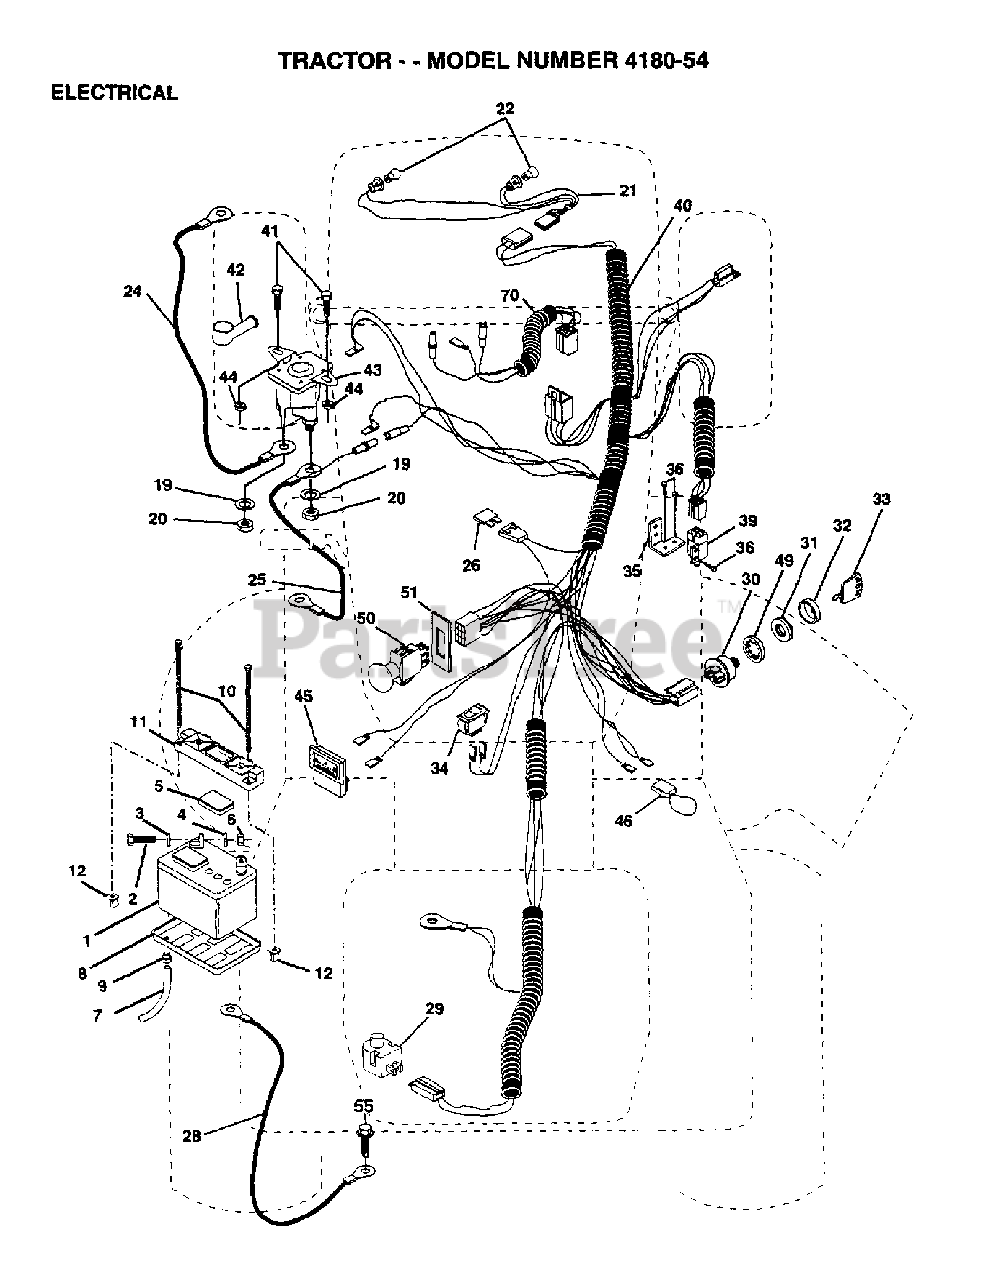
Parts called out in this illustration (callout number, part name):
1	BATTERY
2	BOLT.HEX.1/4.X.3/4.DICHROMATE
3	WASHER
4	LOCKWASHER
5	CAP BATTERY NLA
6	NUT
7	BATT DRAIN TUBE T
8	TRAY.BATTERY
9	HOSE CLAMP T
10	BOLT 1/4-20 X 7.5
20	NUT
22	LIGHTBULB
24	BATTERY CABLE
25	CABLE BATTERY 6 GA 22" W/16W
26	FUSE *
28	CABLE GROUND 6 GA 21" 90T BLK
29	SWITCH SEAT
30	Ignition Switch Kit
31	NUT, IGNITION
32	COVER KEY IGNITIO
33	KEY MLD GEN DELTA
34	SWITCH LT
35	BRACKET LT
39	SWITCH INTERLOCKT
42	TERMINAL COVER
43	Solenoid Kit, .95
44	NUT
46	WIRE PROTECTION LOOP
50	SWITCH-PTO
51	RETAINING RING
55	SCREW LT
